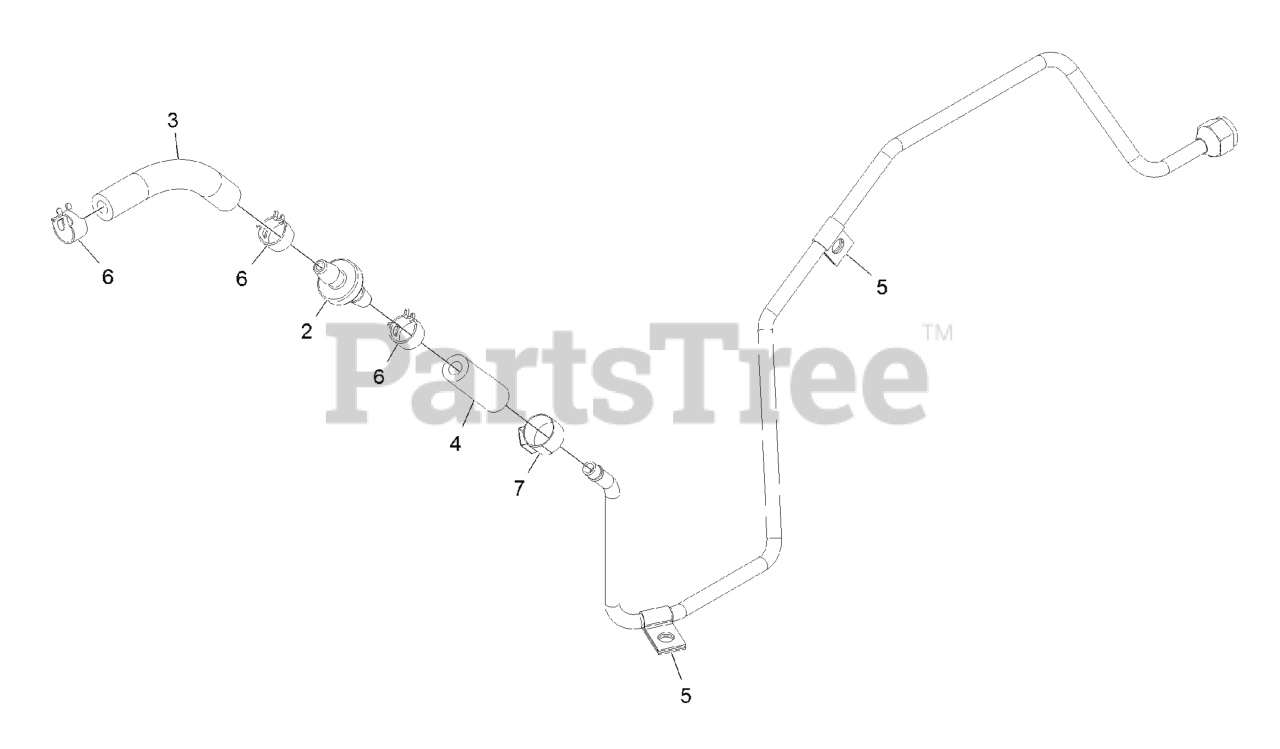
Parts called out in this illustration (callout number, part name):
2	VALVE-CHECK, FUEL
3	HOSE-FUEL
4	Hose-Fuel
5	CLIP-CLOSED, INSULATED
6	CLAMP-HOSE
7	Clamp-Hose, Fuel
